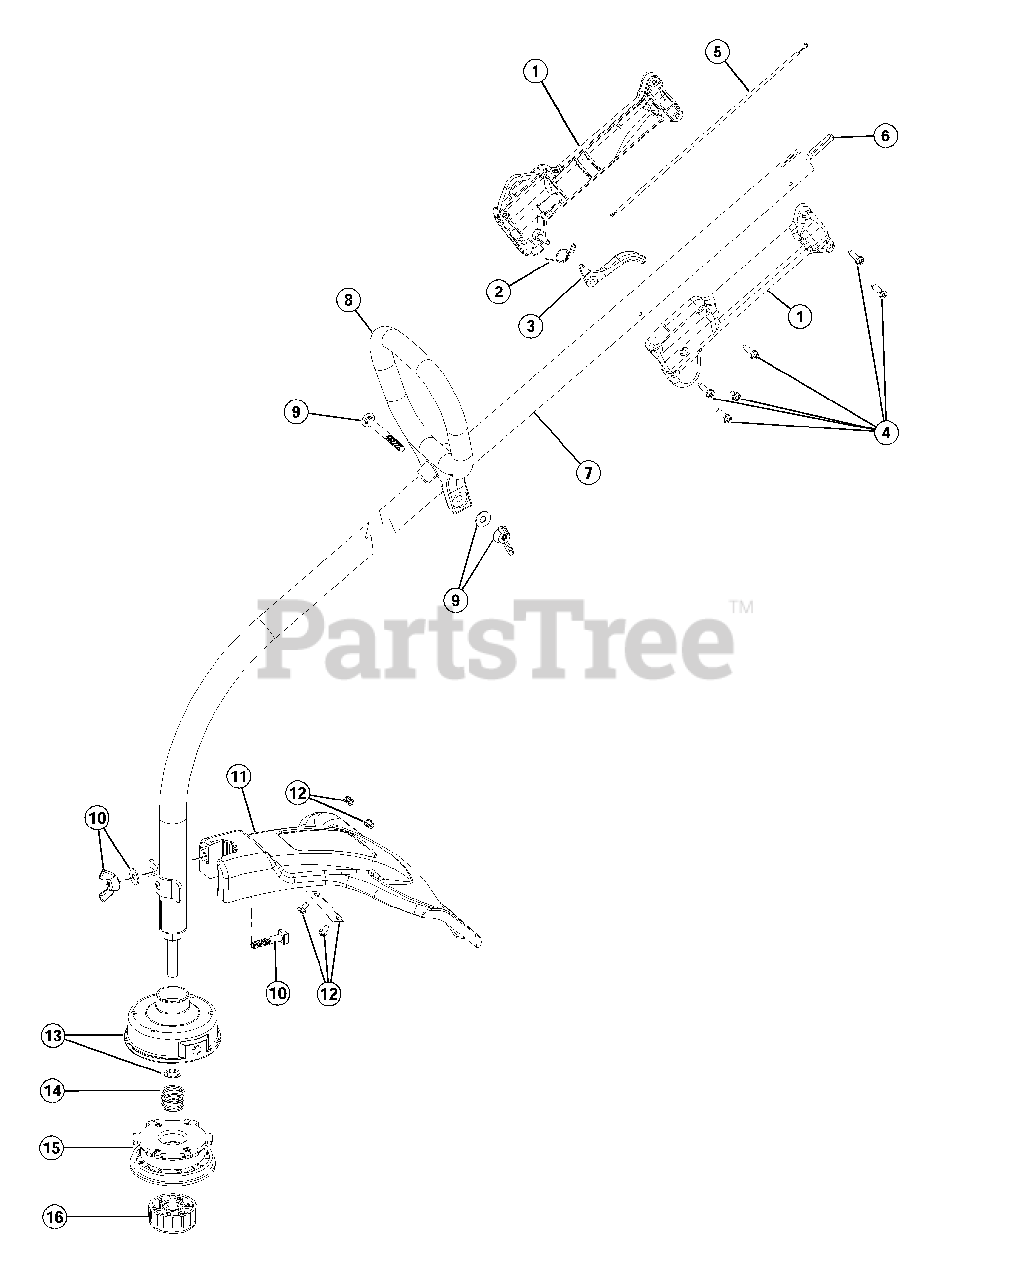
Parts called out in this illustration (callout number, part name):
1	Throttle Housing and Trigger Assembly
2	Throttle Trigger Spring
3	Throttle Trigger
4	Throttle Housing Screws
5	Throttle Cable
6	Flexible Drive Shaft
7	Drive Shaft Housing Assembly
8	D-Handle Assembly
9	D-Handle Hardware
10	Guard Mounting Hardware
12	Blade Assembly
13	Outer Reel w/Retainer
14	Spring
15	Inner Reel
16	Bump Knob
